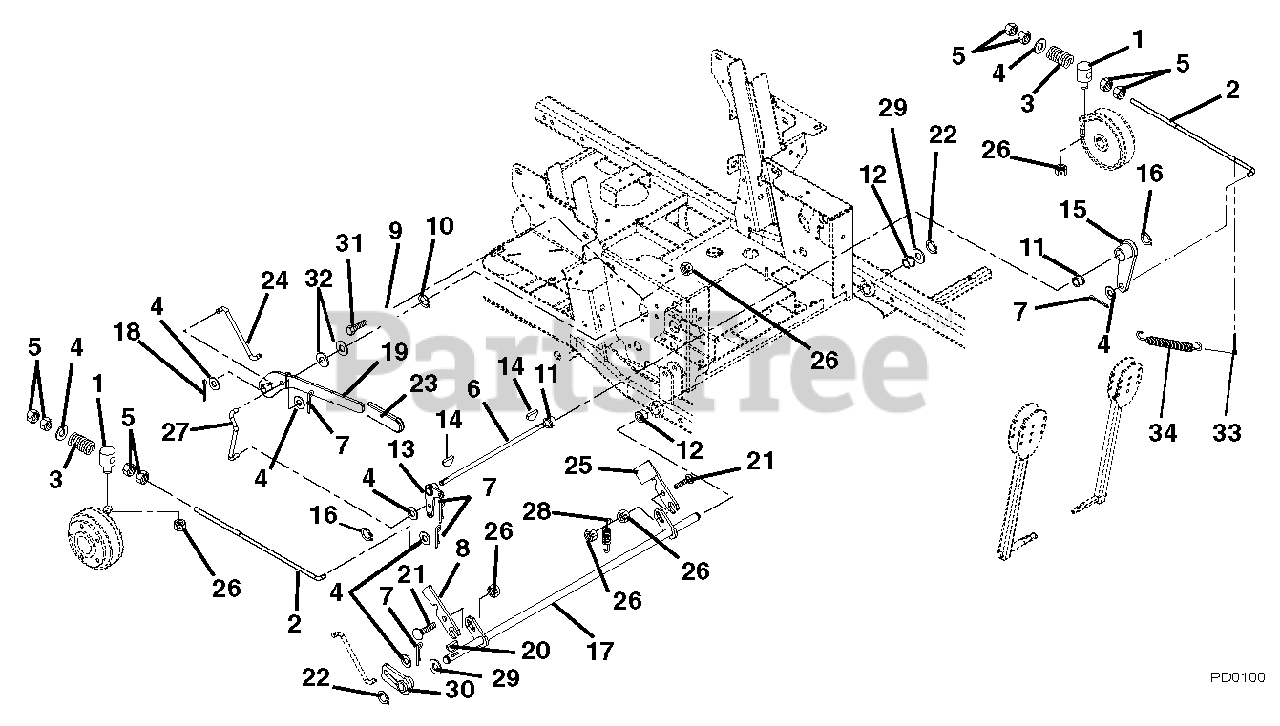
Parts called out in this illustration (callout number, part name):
1	Pivot, Brake Rod
2	Rod, Brake .38 x 19.00
3	Spring, Compression .142 x .710 x 1.75
4	Washer, Flat Steel .406 x .812 x .065
5	Nut, Hex .38-16
6	Shaft, Brake 2.00
7	Pin, Hair
8	Slide, Interlocking Brake
9	Bushing, Flange
10	Ring, Retaining External .625 x .05
11	Bushing, Flange Nylon .762 x 1.00 x .58 x 1.48
12	Bushing, Flange .515 x .75 x .745 x 1.00
13	Weldment, 200 Brake ACT. Arm
14	Key-Square .188X1.00X.188 SAE 8630
15	Weldment, Brake Arm
16	Ring, Retaining External .689 x .078
17	Weldment, Mechanical Brake
18	Pin, Cotter External .09 x .75
19	Weldment, Brake Actuating
20	Key, Woodruff .13 x .63
21	Bolt, Round Head Square Neck .31-18 x 1.25 Grade 5
22	Ring, Retaining External .50 x .05
23	Grip, Handle
24	Linkage, Brake Actuating
25	Interlock, Safety Switch
26	Nut, Locking Top Flange .31-18
27	Linkage, Brake Actuating
28	Spring, Tension .063 x .44 x 1.56
29	Washer, Flat Steel .505 x 1.00 x .062
30	Weldment, Parking Brake Hub
31	Bolt, Hex .31-18 x .75 Grade 5
32	Washer, Flat Steel .630 x 1.250 x .062
33	Pin, Cotter .12 x .75 Extended Prong Square Cut
34	Spring, Extension
